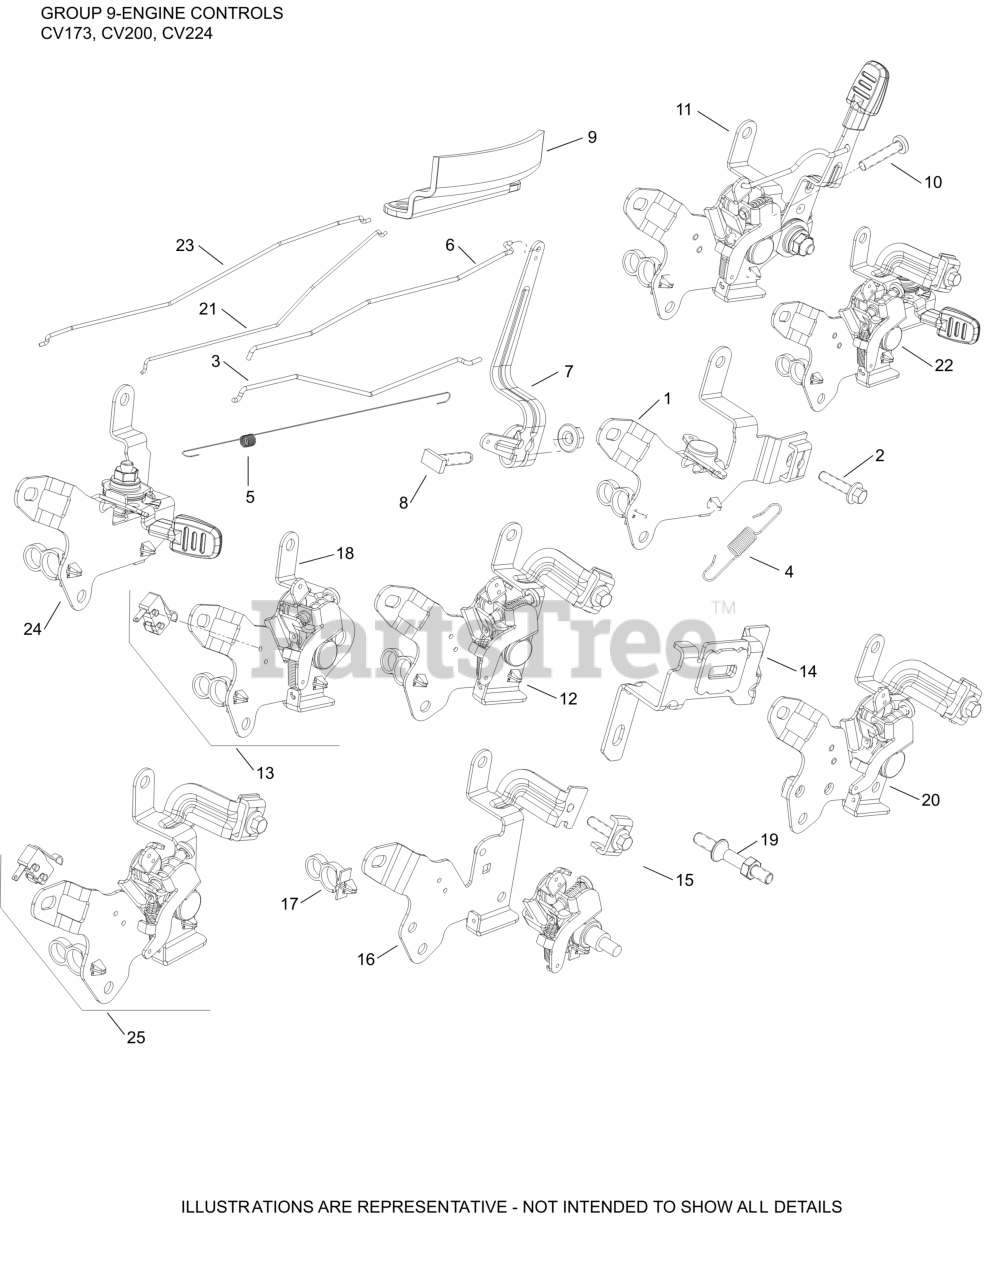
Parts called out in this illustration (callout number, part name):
2	SCREW, (M5) HEX FLANGE
3	LINKAGE, CHOKE
4	SPRING, EXTENSION (GOVERNOR)
5	SPRING, LINKAGE
6	LINKAGE, GOVERNOR
7	LEVER, GOVERNOR
8	SCREW, RECTANGLE HEAD (M6)
10	SCREW, SPEED ADJUSTING
12	CONTROL ASSEMBLY, VARIABLE SPEED-NO KILL
